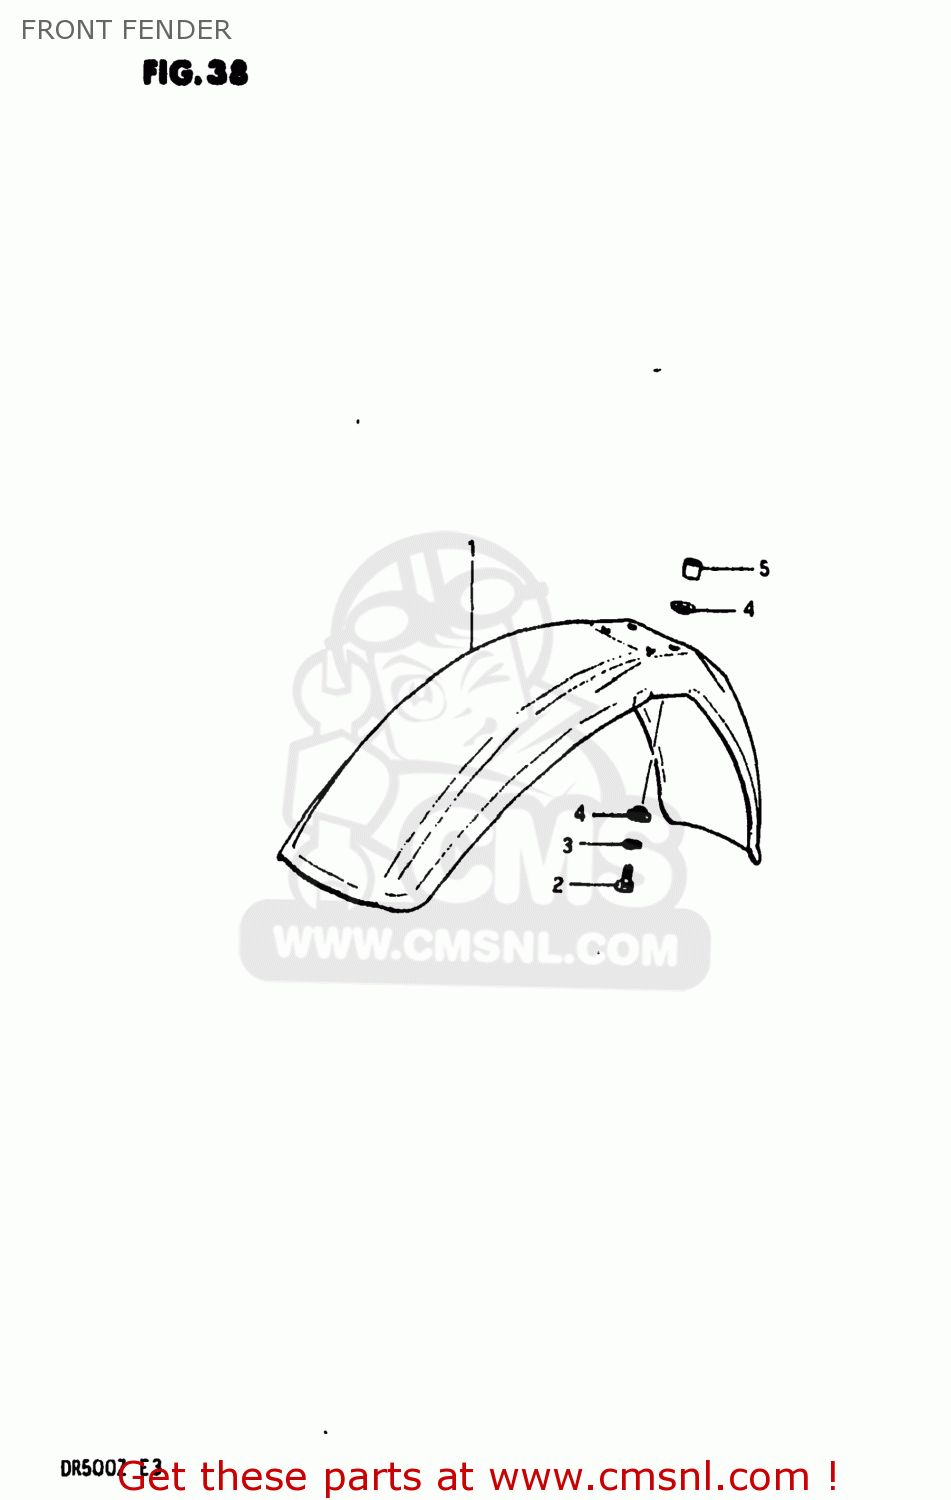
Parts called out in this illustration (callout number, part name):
1	FENDER,FRONT
2	BOLT
3	LOCK WASHER
4	WASHER
5	SPACER (6.8X10X11.5)
